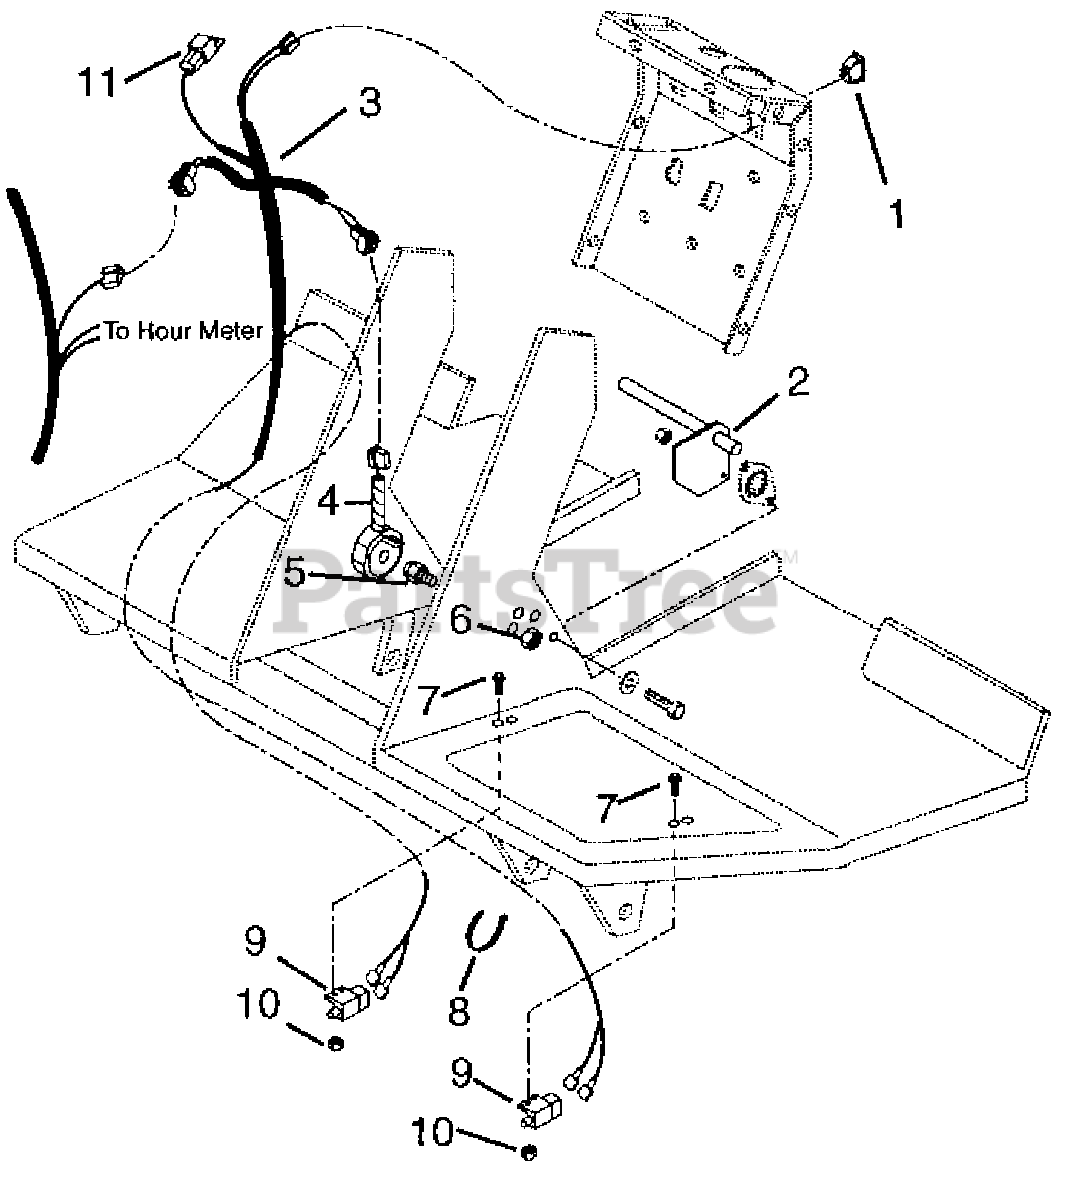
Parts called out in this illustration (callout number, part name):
1	Switch, Cruise
2	Weldment, Control
3	Harness, Wiring
4	Assembly, Magnet
5	Pin, Magnet
6	Nut-Locking-Nylon .50-13
7	Screw-Machine 10-24 x .75 Hex Washer Head
8	Tie Wrap, Black
9	Switch, Interlock
10	Nut-Locking-Nylon 10-24 with insert
11	Relay
